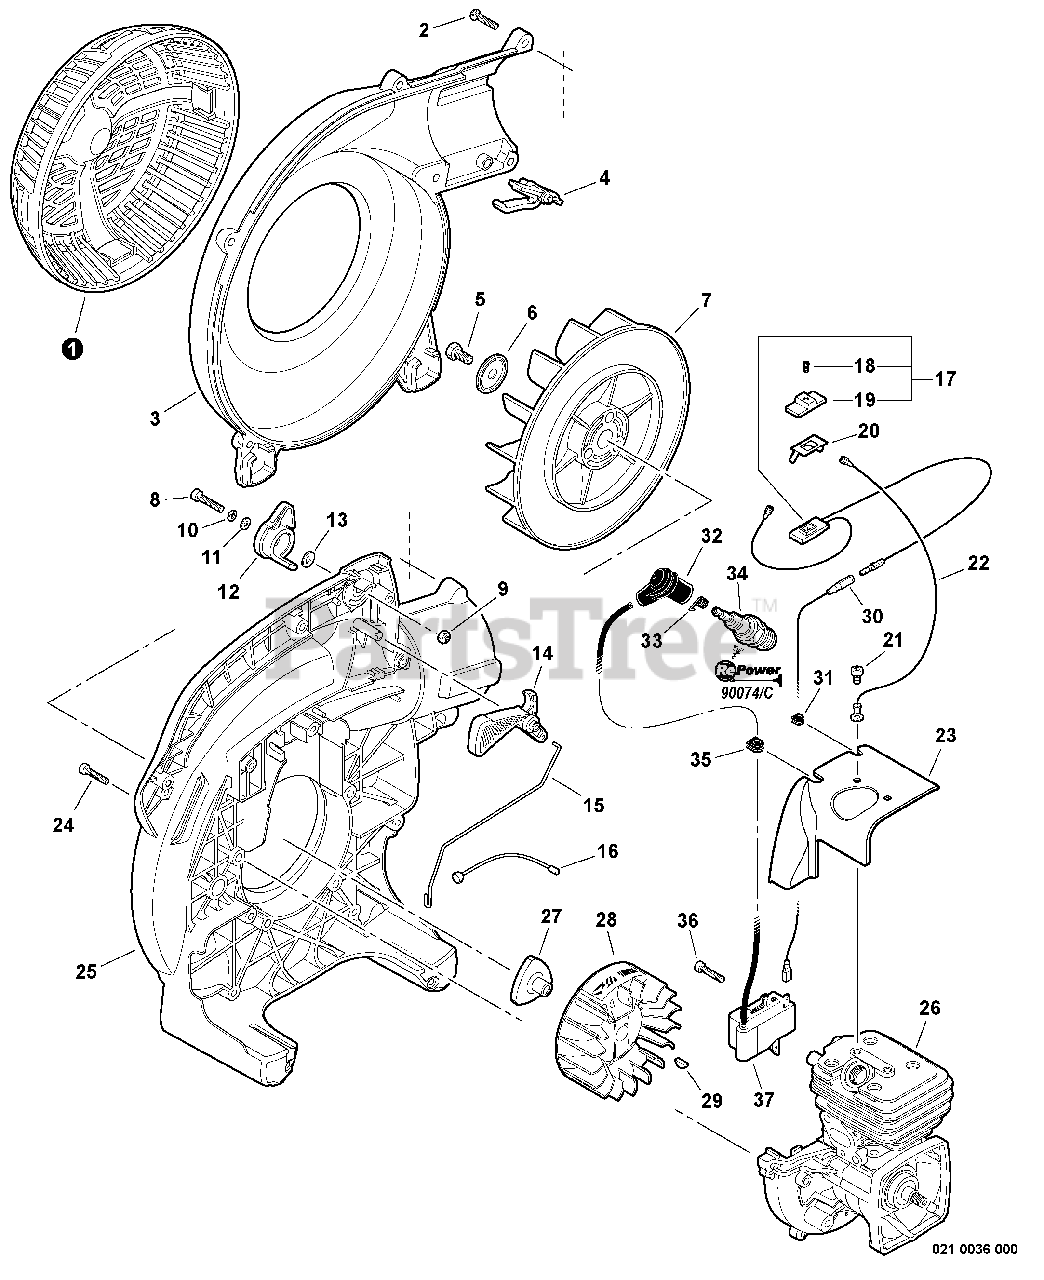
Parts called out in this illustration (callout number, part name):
1	GUARD, FAN
2	BOLT, TORX 5×20
3	COVER, FAN
4	LOCK, TUBE
5	BOLT 8×14
6	WASHER 8.2×31×0.8
7	FAN, BLOWER
8	BOLT, TORX 5×25
9	NUT, LOCK M5
10	WASHER, SPRING 5
11	WASHER 5.3×10×1
12	CONTROL, THROTTLE
13	WASHER 5.5×12×0.8
14	TRIGGER, THROTTLE
15	ROD, THROTTLE
16	CABLE, THROTTLE
17	SWITCH ASSY, ON-OFF
18	SCREW 3×10
19	KNOB, SWITCH
20	TERMINAL, LEAD
21	BOLT, TORX 5×8
22	LEAD L= 210 MM
23	SHIELD, CYLINDER
24	BOLT, TORX 4×20
25	CASE, FAN
26	SHORT BLOCK
27	HUB, FAN
28	FLYWHEEL
29	KEY, WOODRUFF
30	LEAD L= 85 MM
32	CAP, SPARK PLUG
33	TERMINAL, SPARK PLUG
34	SPARK PLUG - BPM8Y
34	SPARK PLUG - BPMR8Y
36	BOLT, TORX 4×20
37	COIL, IGNITION
38	TUNE-UP KIT - REPOWER
